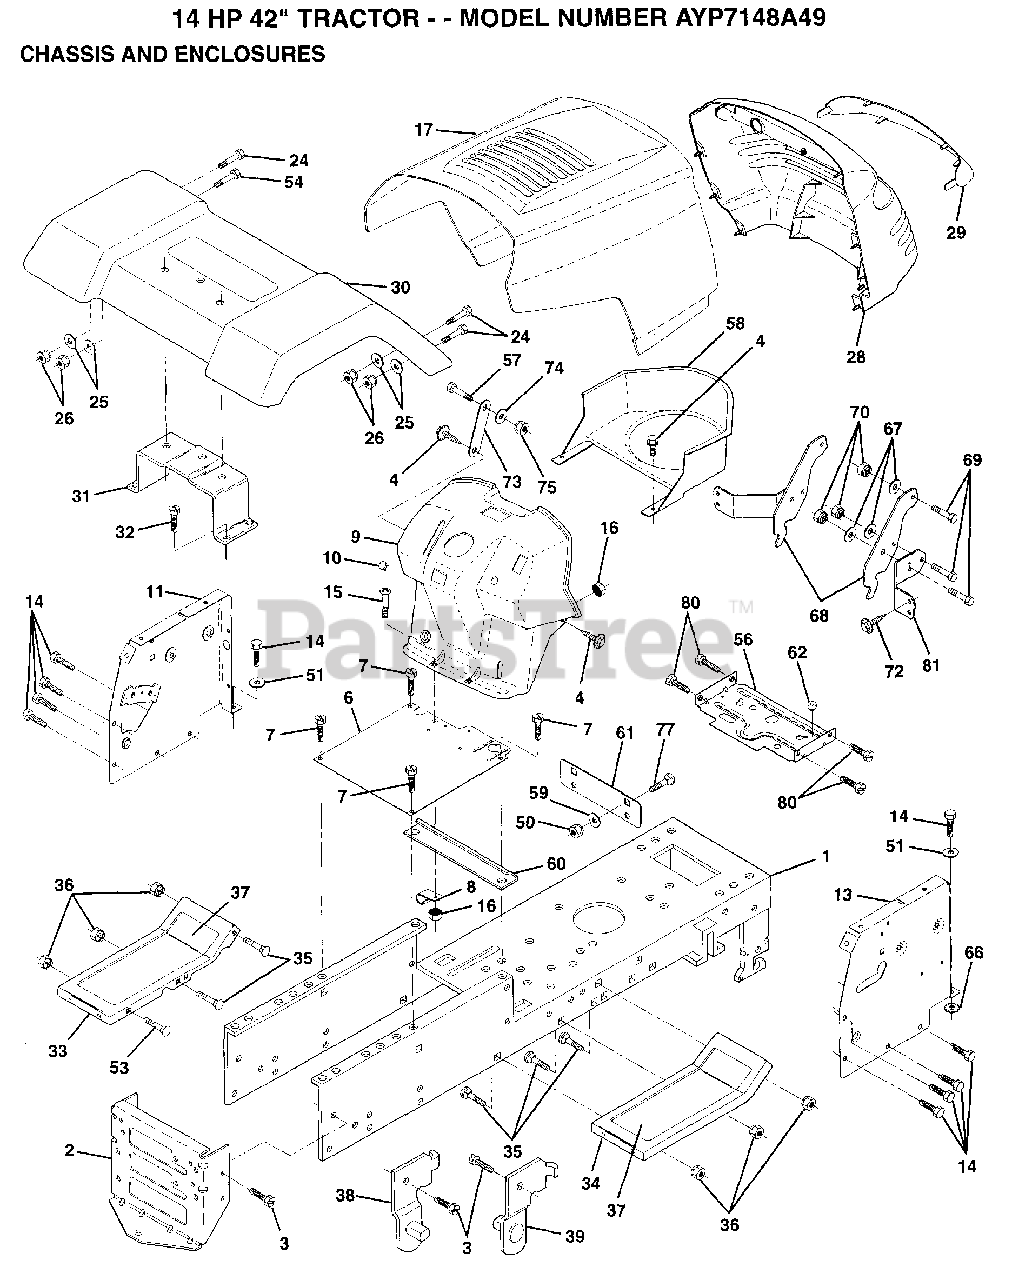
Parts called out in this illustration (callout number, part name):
3	SCREW
4	SCREW HEX CRT
6	SADDLE LT SADDLE SHIFT
7	SCREW GTV
8	CLIP T
10	PLUG BUTTON T
11	PANEL ASM DASH
14	SCREW LT
16	NUT
25	WASHER
29	HANDLE.LIFT.LH.
30	FENDER
31	BRKT FENDER
32	SCREW
35	BOLT
37	FOOTREST PAD
38	BRACKET ASM LH
39	BRACKET ASM RH
50	NUT
51	WASHER
57	SCREW
58	DUCT AIR 12-15H
59	WASHER
60	SPACER FENDER LT
61	PLATE EXTEN FEND
66	LOCKWASHER
67	WASHER
68	HING PICK-OFF HD
69	BOLT LT
73	BRACE SUPT DASH
74	WASHER
75	NUT
77	BOLT D
81	BRACKET GRILLE
